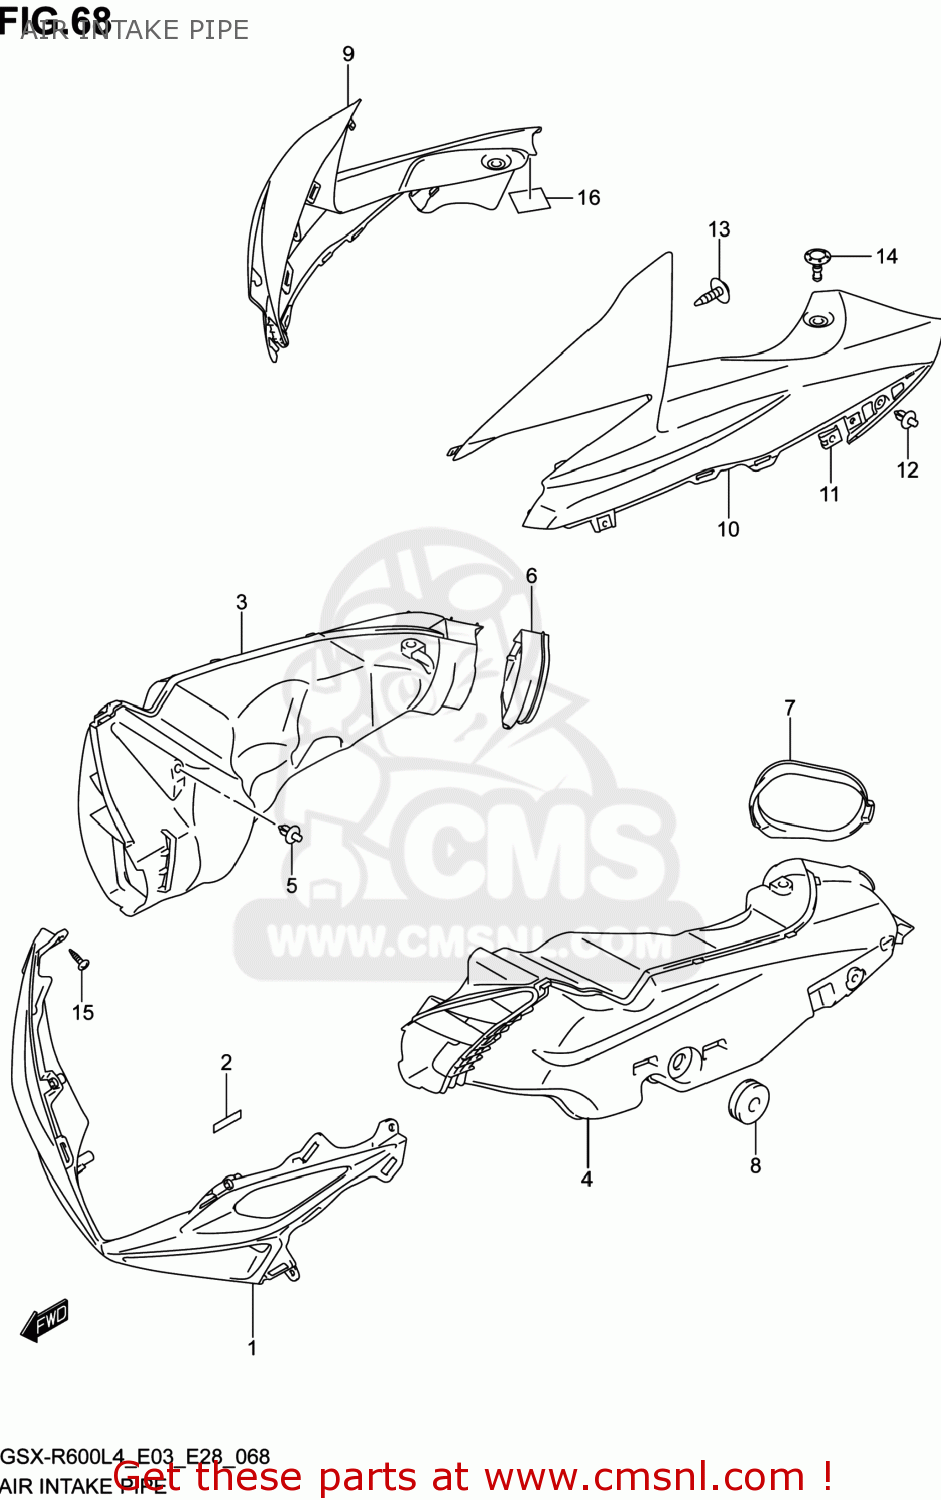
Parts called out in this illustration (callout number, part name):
1	COVER,INTAKE
2	TAPE(6X25X0.13)
3	PIPE,AIR INTAKE,R
4	PIPE,AIR INTAKE,L
5	CLIP(BLACK)
6	MOLDING,AIR INTAKE,R
7	MOLDING,AIR INTAKE,L
8	CUSHION
9	COVER,INTAKE,R
10	COVER,INTAKE,L
11	NUT
12	CLIP(BLACK)
13	SCREW(5X12)
14	CLIP
15	SCREW
16	PROTECTOR,BATTERY
